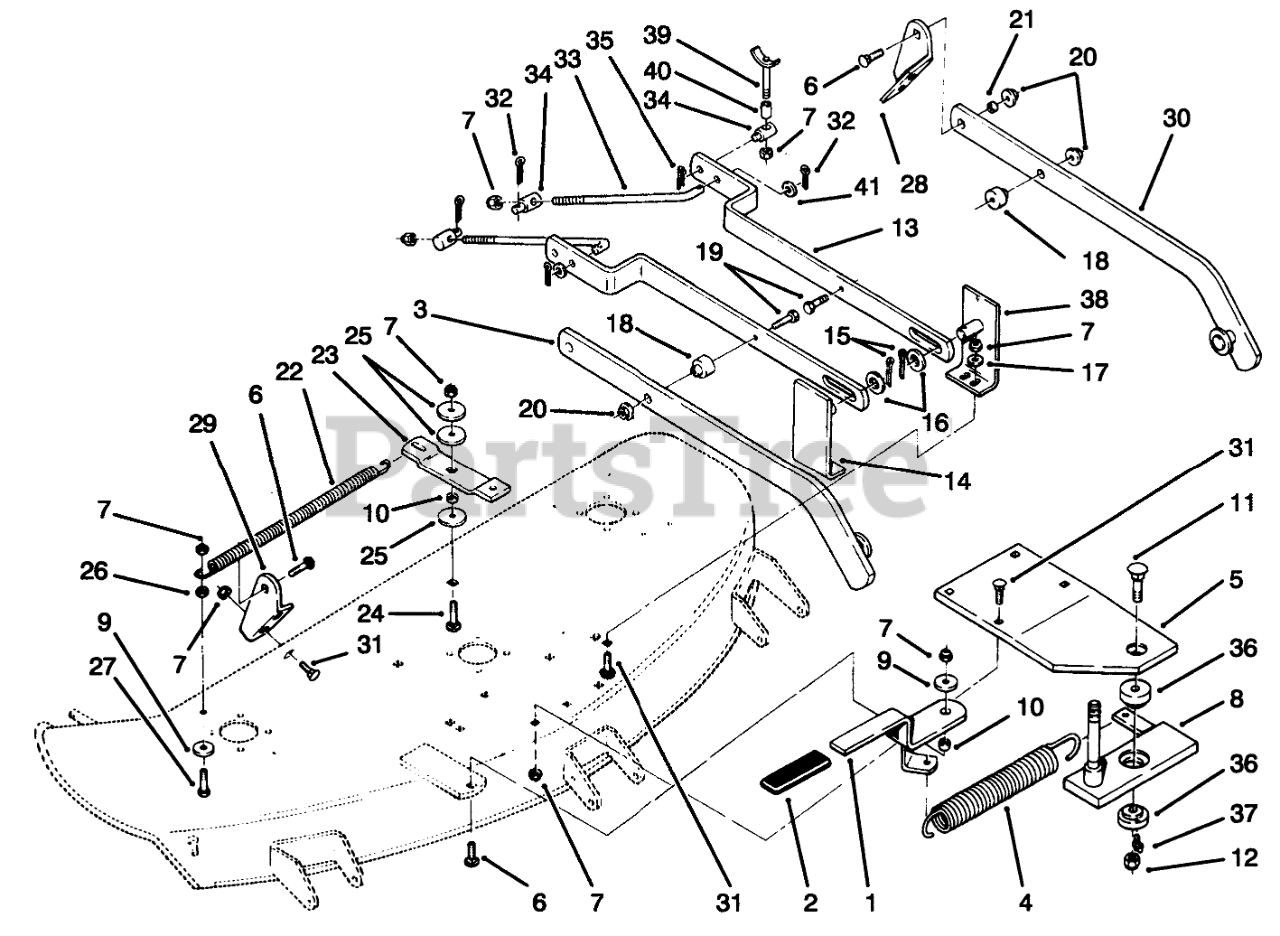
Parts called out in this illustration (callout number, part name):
1	Lever
3	Draft Bar RH
4	Spring
5	Plate
6	BOLT-CARR
7	NUT-LOCK, NI
8	Countershaft
9	WASHER
10	Spacer
11	Bolt
12	NUT-LOCK, NI
13	Bar-Leveler
14	Bracket L.H.
15	PIN-COTTER
16	WASHER-FLAT
17	WASHER-FLAT
18	SPACER
19	SCREW-HH
20	LOCKNUT-FLANGE
21	SPACER
22	SPRING - EXTENSION
23	Arm-Idler
24	SCREW-CARR
25	Washer
26	NUT-HEX
27	SCREW-HH
28	Bracket LH
29	Bracket RH
30	Draft Bar LH
31	BOLT-CARR
32	PIN-COTTER
34	TRUNNION
35	Hairpin Cotter
36	BUSHING
37	Fitting-Grease
38	Bracket R.H.
39	WLDMT-HANGER ROD
40	SPACER .375 ID X 1.6
41	WASHER-PLAIN
